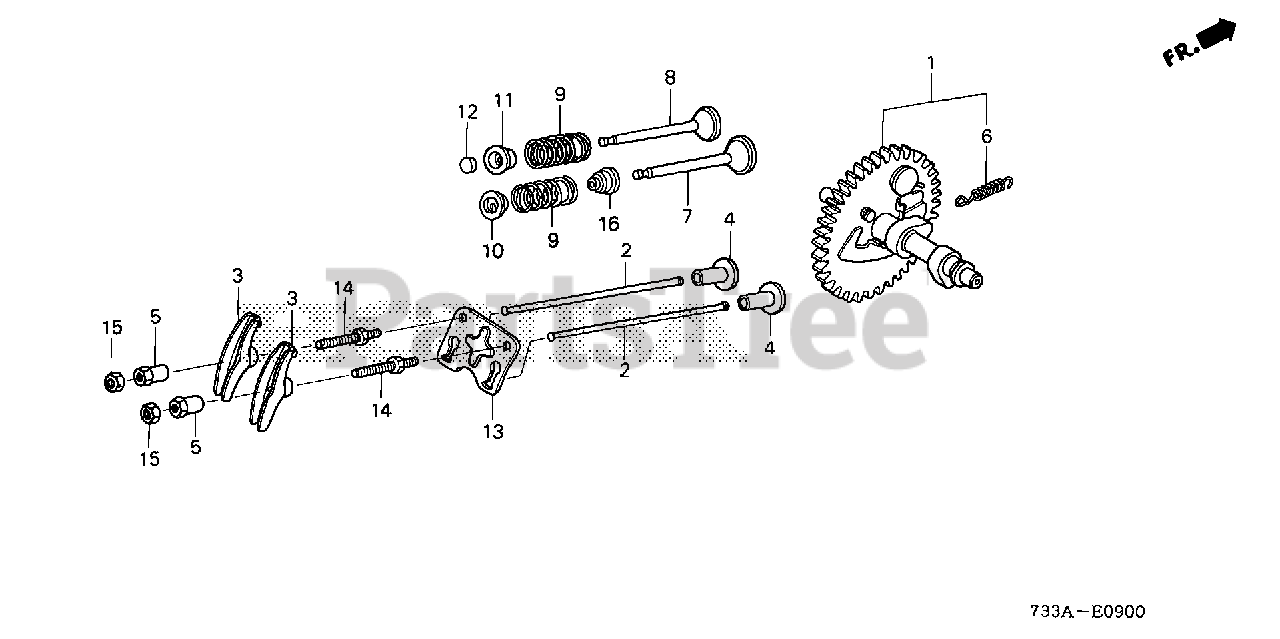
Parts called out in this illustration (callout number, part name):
1	CAMSHAFT ASSY.
2	ROD, PUSH
3	ARM, VALVE ROCKER
4	LIFTER, VALVE
5	PIVOT, ROCKER ARM
6	SPRING, WEIGHT RETURN
7	VALVE, IN.
8	VALVE, EX.
8	VALVE, EX. (STELLITE)
9	SPRING, VALVE
10	RETAINER, IN. VALVE SPRING
11	RETAINER, EX. VALVE SPRING
12	ROTATOR, VALVE
13	PLATE, PUSH ROD GUIDE
14	BOLT, PIVOT (6MM)
14	BOLT, PIVOT (8MM)
15	NUT, PIVOT ADJUSTING
